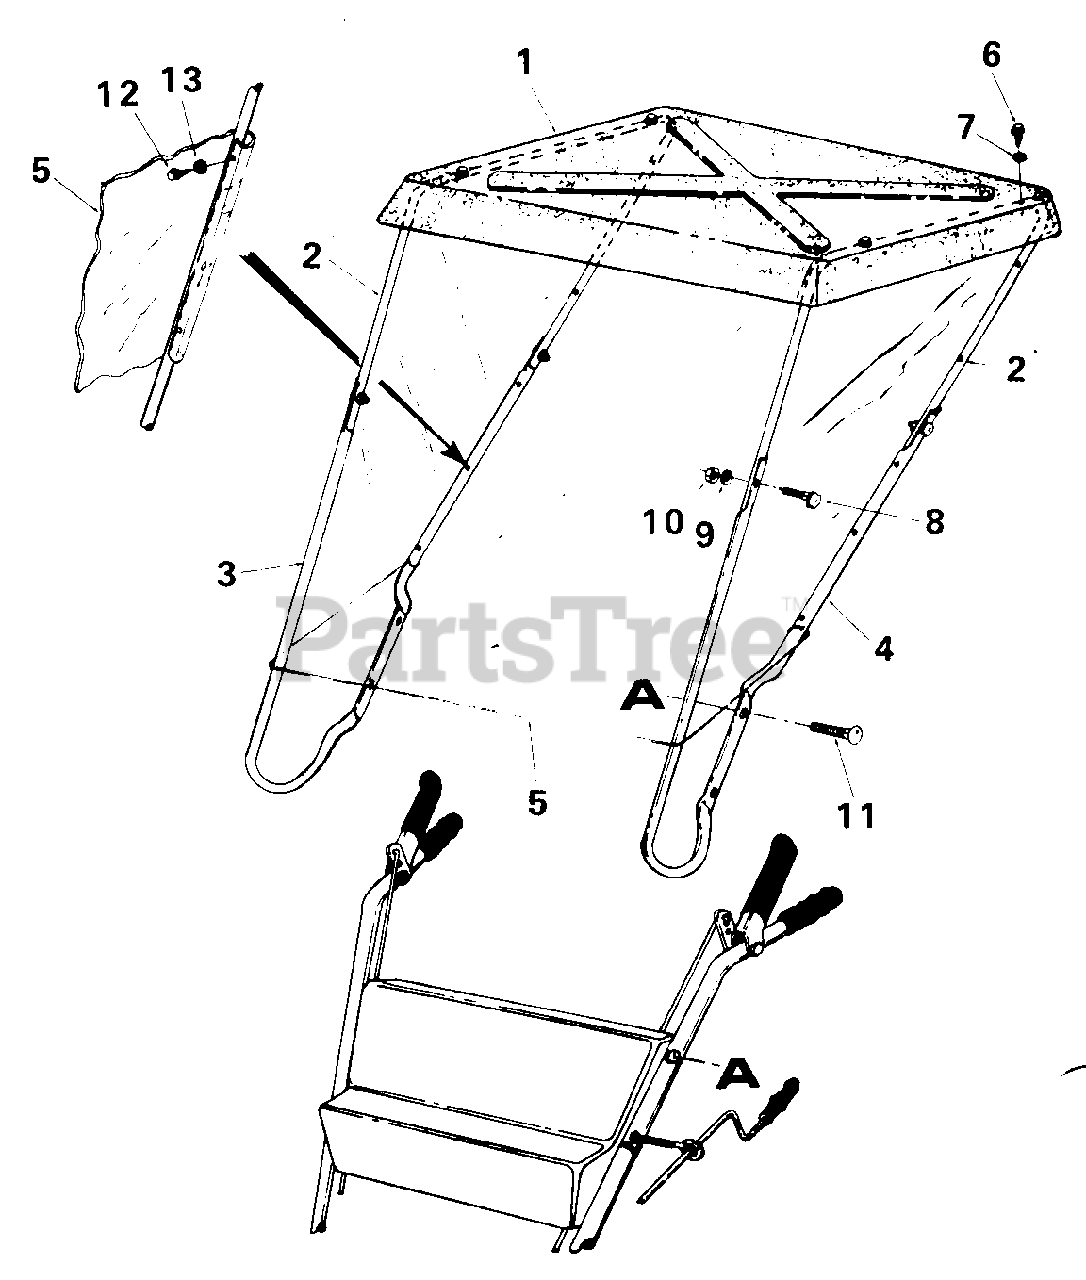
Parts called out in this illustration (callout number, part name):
1	Enclosure Roof
2	Upper Frame
3	Lower Frame-R.H.
4	Lower Frame-L.H.
5	Clear Plastic Windshield
6	Hex "AB" Tap Scr. 1/4 x .62" Lg.
7	Fl. Wash. .281" I.D. x.73" O.D.
8	Curved Hd. Carr. Bolt 5/16-18 x 1.38" Lg.
9	Lock Wash. 5/16" I.D.*
10	Hex Nut 5/16-18 Thd.*
11	Curved Hd. Carr. Bolt 5/16-18 x 2. 25" Lg.
12	Hex Wash. Hd. "AB" Tapp Scr. #10 x .50"
13	Rubber Wash. .18" I.D. x.50" O.D.
